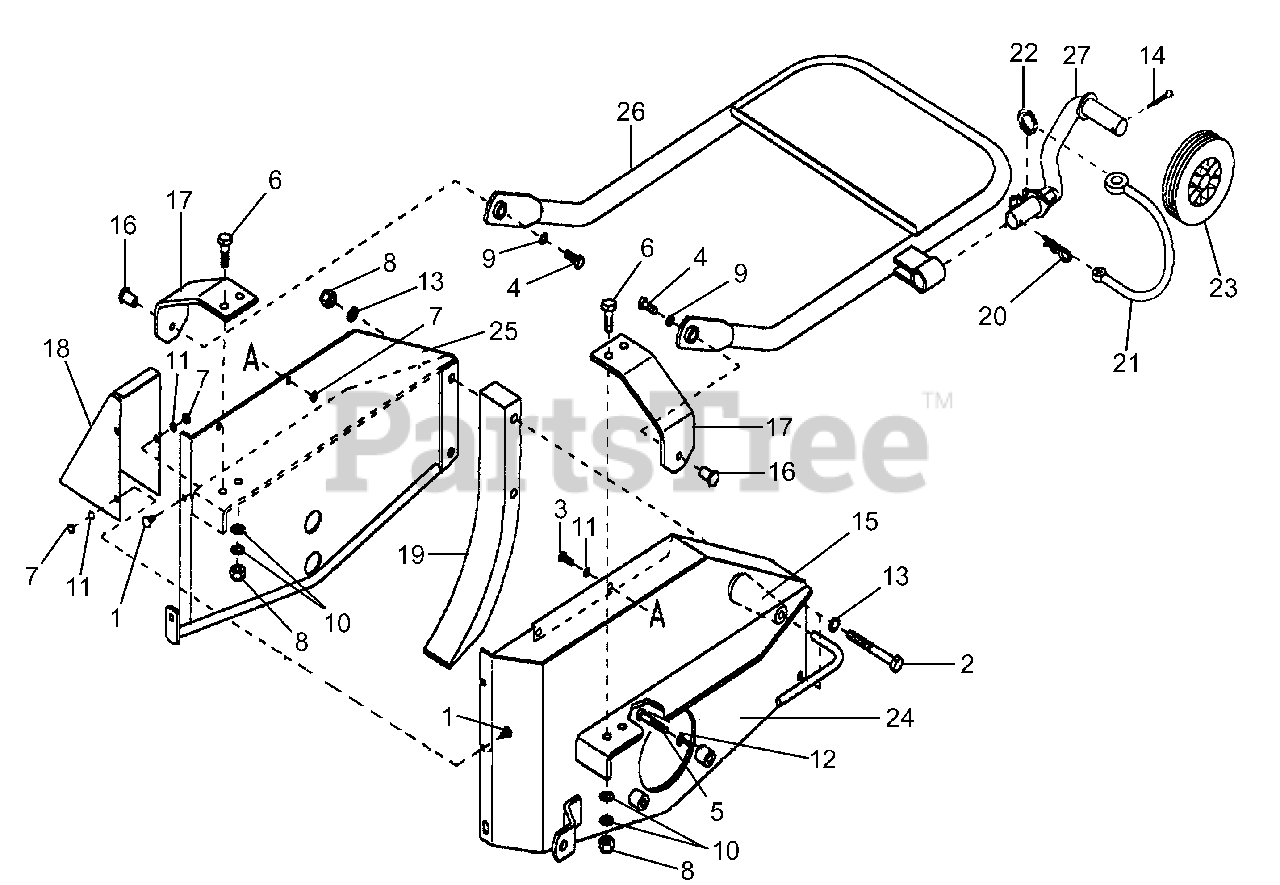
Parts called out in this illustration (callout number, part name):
1	BOLT M6X12 AND SQUARE NUT
2	HEX SCREW M10X85 UNI 5739 5S
3	HEX. SCREW M6X16 UNI 5739-8G
4	HEX. SCREW M8X20 UNI 5739-8G
5	HEX SCREW M8X50 UNI 5739-8G
6	HEX. SCREW M10X30 UNI 5739-8G
7	NUT M6 UNI 5588-5S
8	LOCKNUT M 10
9	WASHER P.8,4X17 UNI 6592
10	FLAT WASHER10.5X18 UNI6592AC.
11	TOP WASHER 6 DIN 6796
12	SUPER WASHER 8 DIN6796 GALV.
13	TOP WASHER 10
14	COTTER PIN 4X30
24	SIDE PANEL LH
25	SIDE PANEL RH
27	SPINDLE ARM
